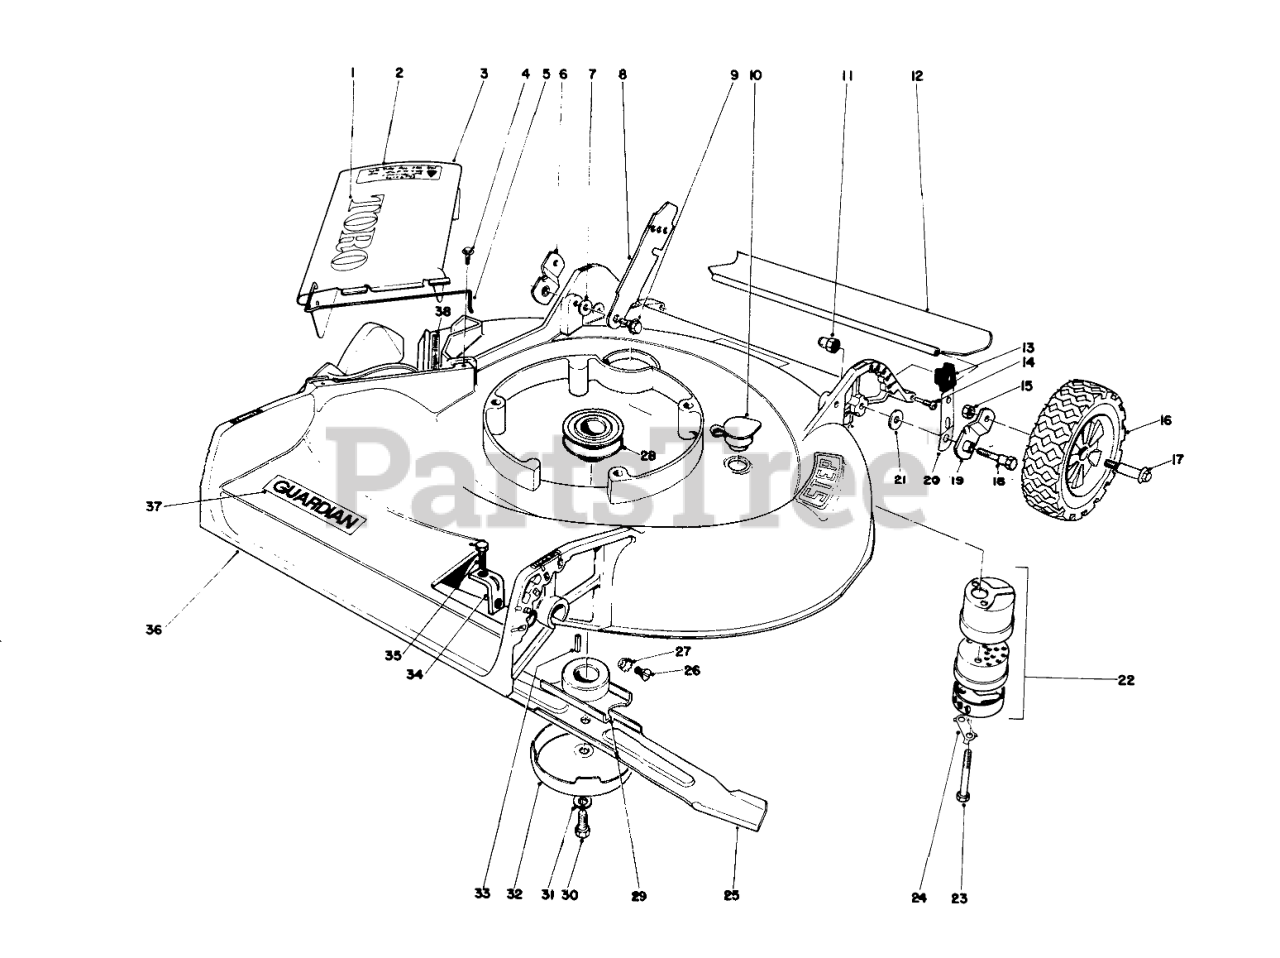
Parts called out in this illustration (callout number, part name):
1	TORO LOGO DECAL
2	Caution Decal
3	Deflector Cover Assembly (Incl. Ref. #1-2 & 5)
4	SCREW
5	SPRING HINGE
6	Pivot Arm
7	SPACER
8	Latch
9	SCREW-SHOULDER
10	WASHOUT PLUG
11	HANDLE PIVOT NUT
12	REAR SAFETY SHIELD 21
13	KNOB-ARM
14	SAFTEY SHIELD SCREW
15	Nut
16	WHEEL TIRE ASM 8 IN
17	BOLT-WHEEL
18	5/16-18 PIVOT SCREW
19	Pivot Arm
20	SPRING ARM ASM
21	WASHER-PIVOT
22	Muffler Assembly (Incl. Ref. #23 & 24)
23	SCREW-HH
24	CLIP - LOCKING
25	Blade
26	5/16-18X5/8 FLT HD MS
27	Lockwasher
28	DRIVER PULLEY
29	Blade Retailer
30	SPECIAL SCREW
31	WASHER-LOCK
32	AntiScalp Cup
33	KEY-SQUARE
34	Bracket-Gear Box
35	SCREW-HH
36	Housing
37	Decal
38	Decal
